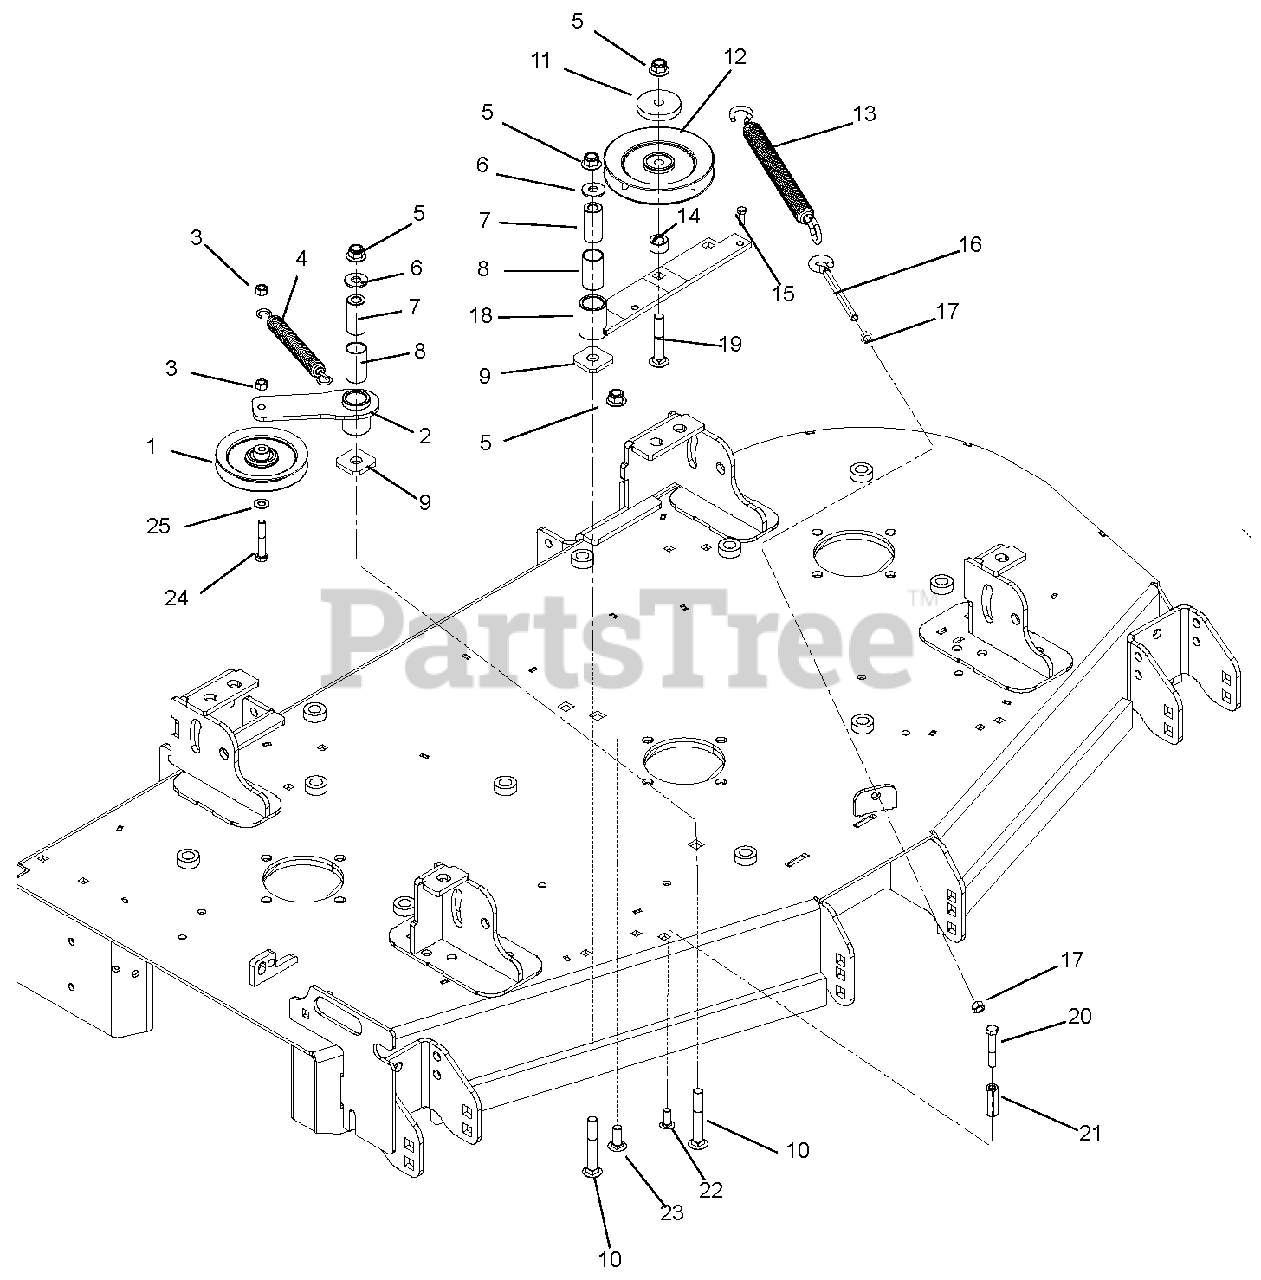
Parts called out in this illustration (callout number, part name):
1	Sheave, .38" ID x 5.00" OD V-Idler
2	Weldment, Idler Arm
3	Nut, Locking Center .38-16
4	Spring, Extension
5	Nut, Locking Nyloc Flange .50-13
6	Washer, Flat Steel .563 x 1.38 x .109
7	Bushing, Spacer .505/.500 x .999/.996 x 2.05/2.03
8	Bushing 1.00 x 1.125 x 1.936
9	Washer, Flat .640 x 1.75 x .250
10	Bolt, Round Head Square Neck .50-13 x 3.50 Grade 5
11	Cap, Idler Bearing Sealing
12	Sheave, .50" ID x 6.00" OD V-Idler
13	Spring, Extension
14	Bushing, Spacer .502 x .997 x .50
15	Bolt, Shoulder EP .38-16 x .30 Hex
16	Bolt, .38-16 x 5.50 .62 Diameter Eye
17	Nut, Hex Jam .375-16
18	Weldment, Idler Arm
19	Bolt, Round Head Square Neck .50-13 x 3.00 Grade 5
20	Bolt, Hex .38-16 x 1.75 Grade 5
21	Nut, Cupling .375-16 x 1.75
22	Bolt, Round Head Square Neck .38-16 x 1.00
23	Bolt, Round Head Square Neck .50-13 x 1.50 Full Thread Grade 5
24	Bolt, Hex .38-16 x 2.25 Grade 5
25	Washer, Flat Steel .406 x .812 x .065
